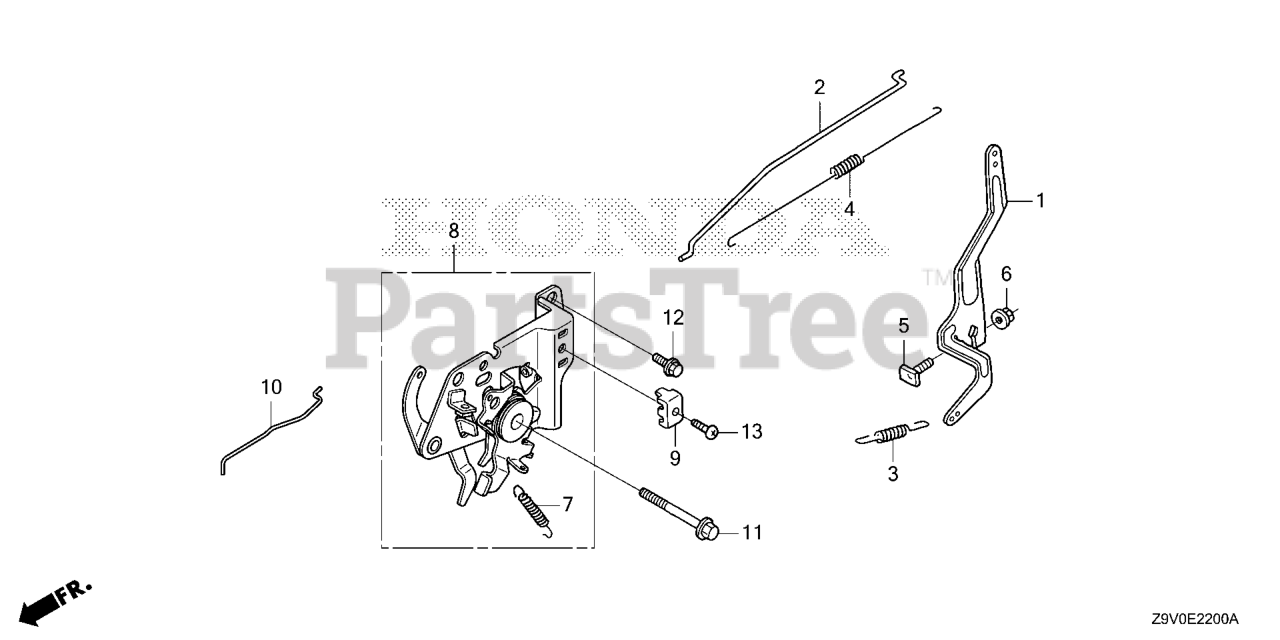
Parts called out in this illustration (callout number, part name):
1	ARM, GOVERNOR
2	ROD, GOVERNOR
3	SPRING, GOVERNOR
4	SPRING, THROTTLE RETURN
5	BOLT, GOVERNOR ARM
6	NUT, FLANGE (6MM)
